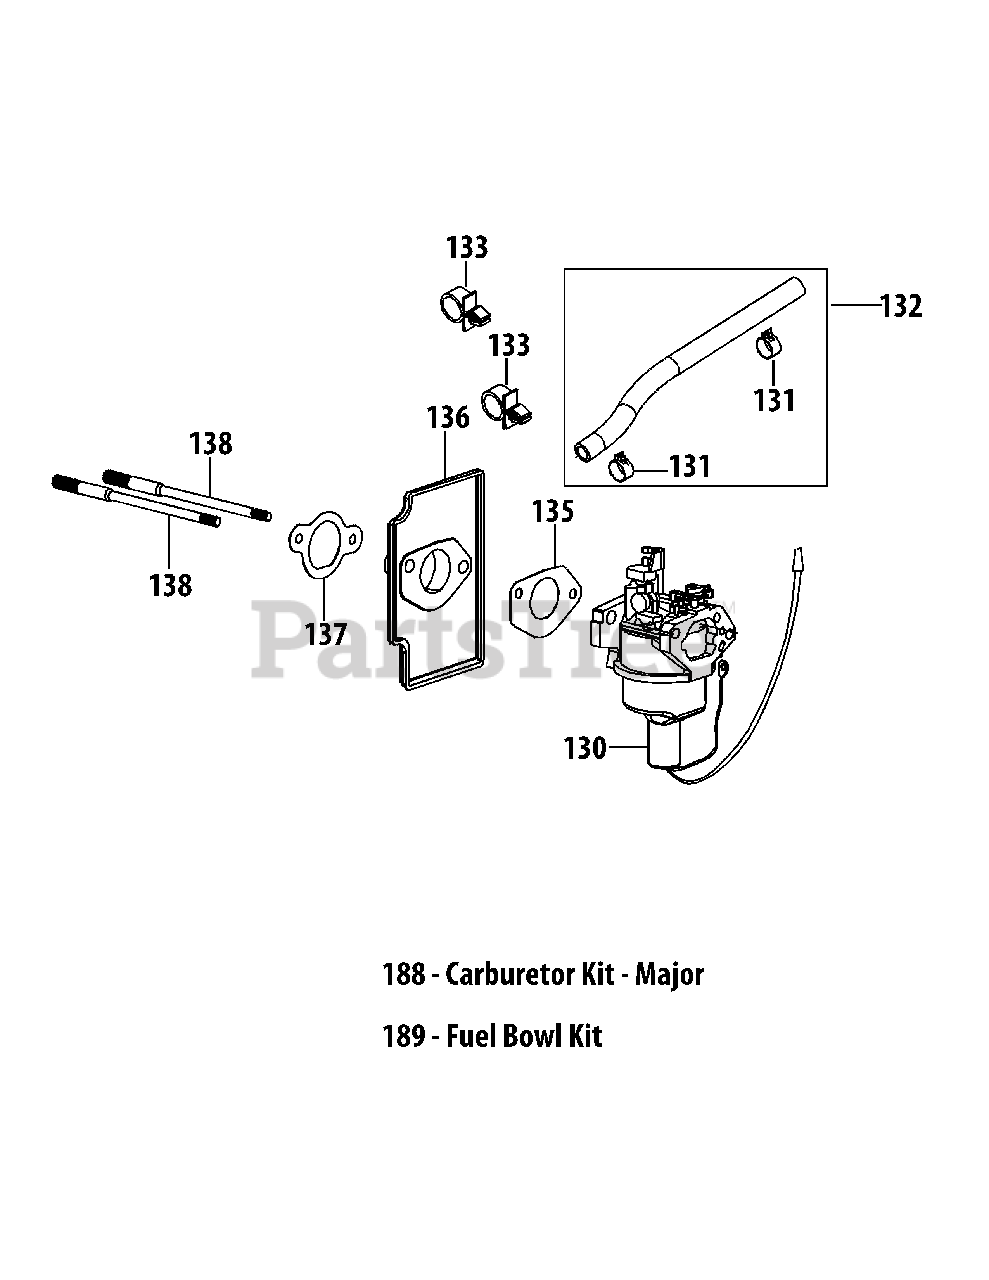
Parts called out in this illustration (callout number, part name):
130	Carburetor Assembly (Hy-4P90F)
131	Fuel Hose Clamp
132	Fuel Line Kit
133	Plastic Support Clamp
135	Carburetor Gasket
136	Carburetor Insulator
137	Carburetor Insulator Gasket
188	Carburetor Kit - Major
189	Fuel Bowl Kit
